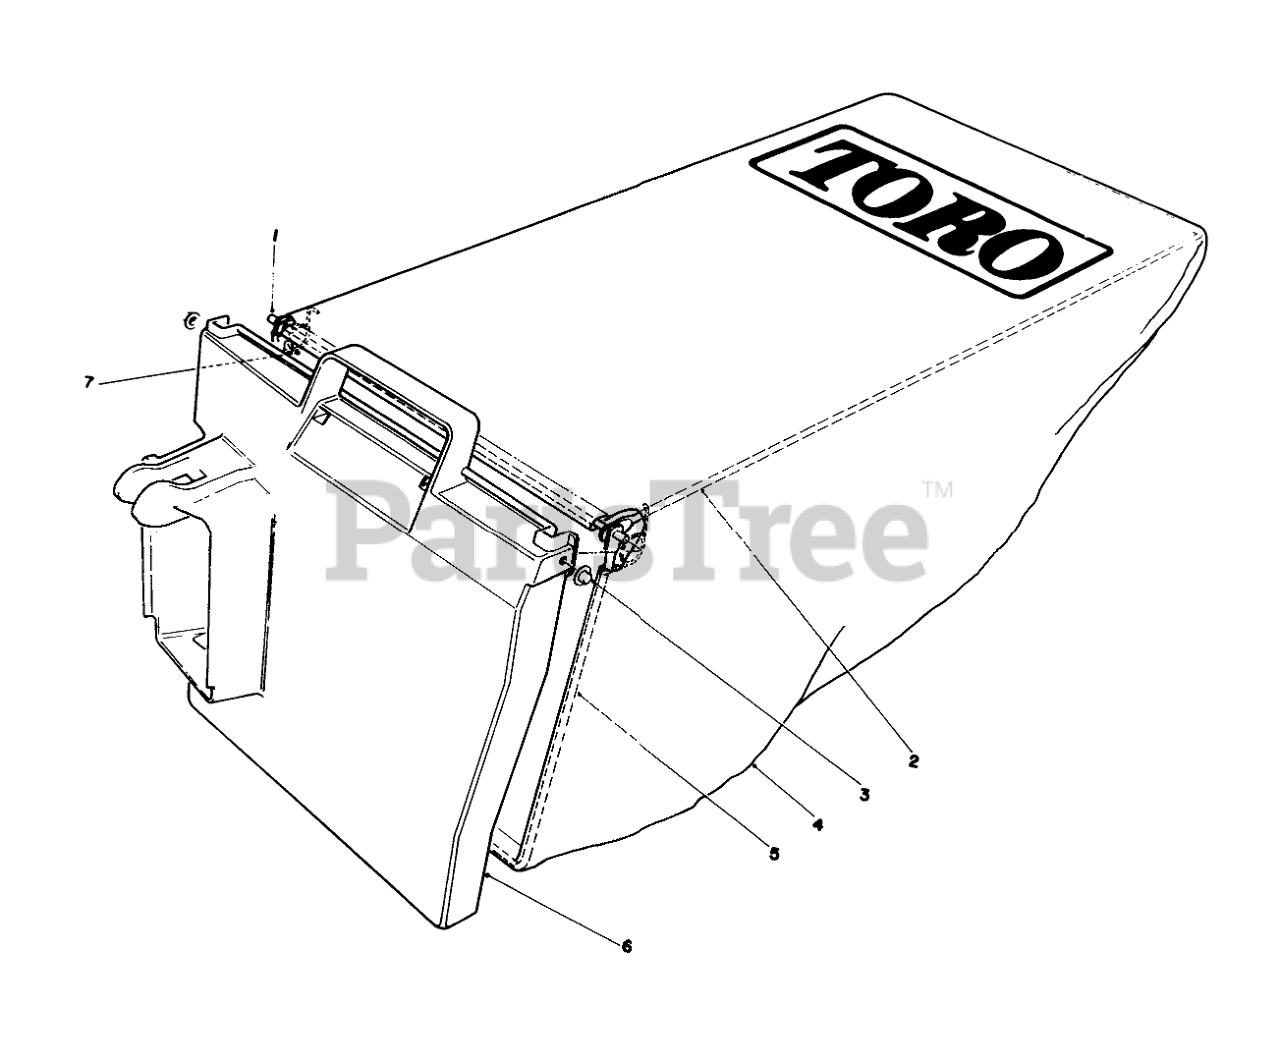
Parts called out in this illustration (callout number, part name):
1	HINGE PIN
2	BAG FRAME
3	NUT-PUSH
5	BAG FRAME
6	Door-Bag
7	SPRING
